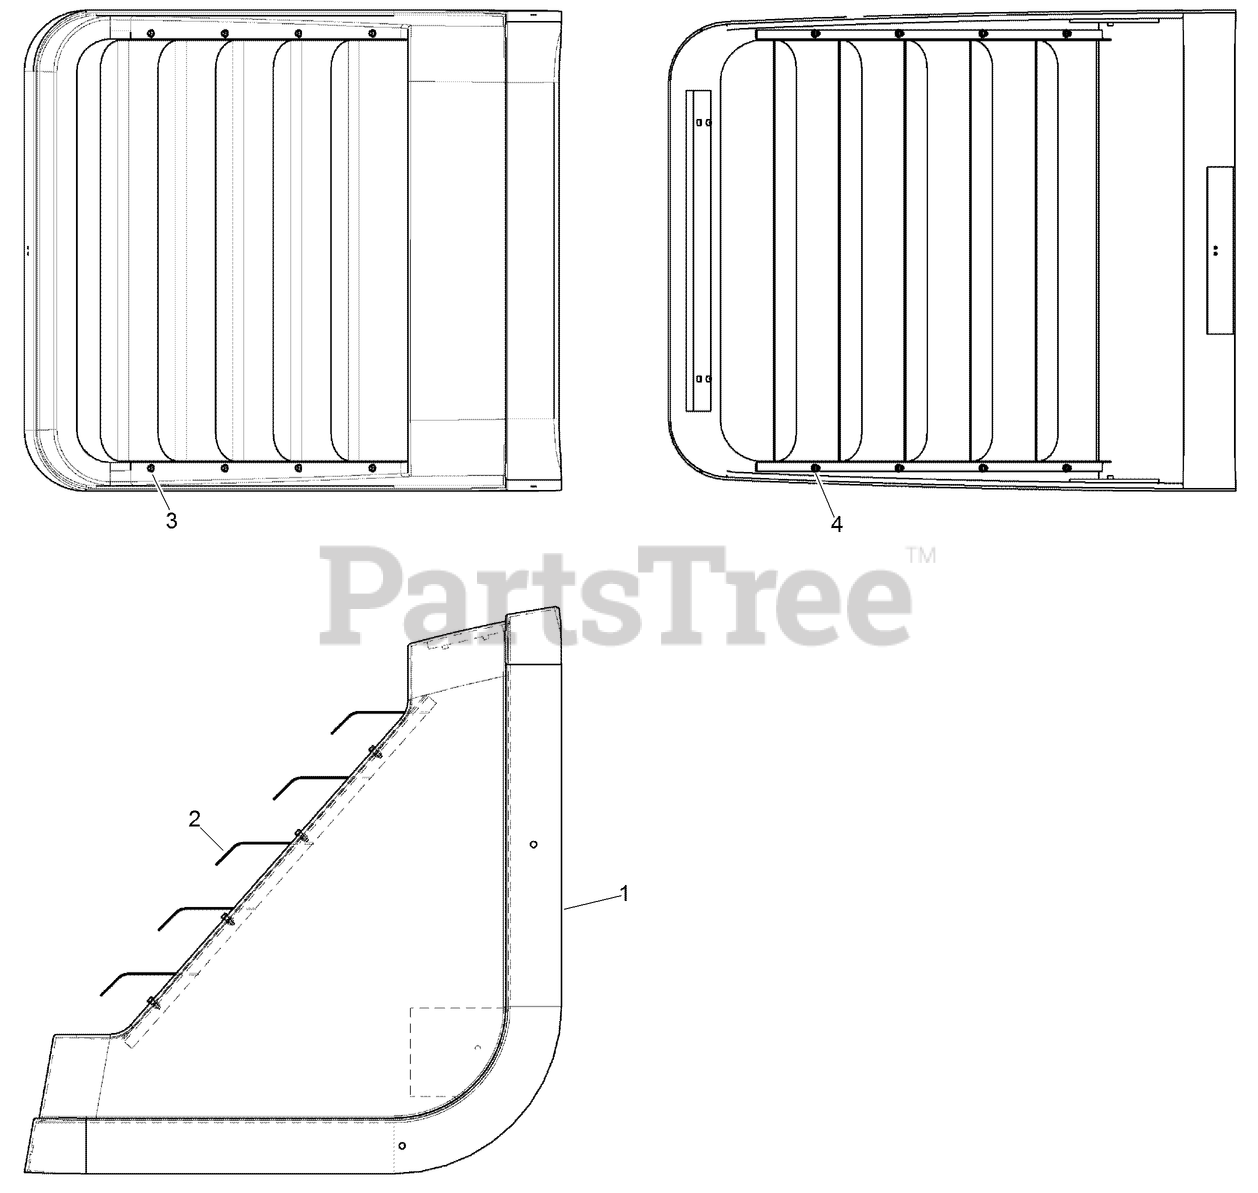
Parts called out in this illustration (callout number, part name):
1	HOOD - Rear, Fiberglass
2	WELDMENT - Rear Hood Louver
3	SCREW-HHF
4	NUT, METRIC FLANGE PREVAILING - M6 Zinc
